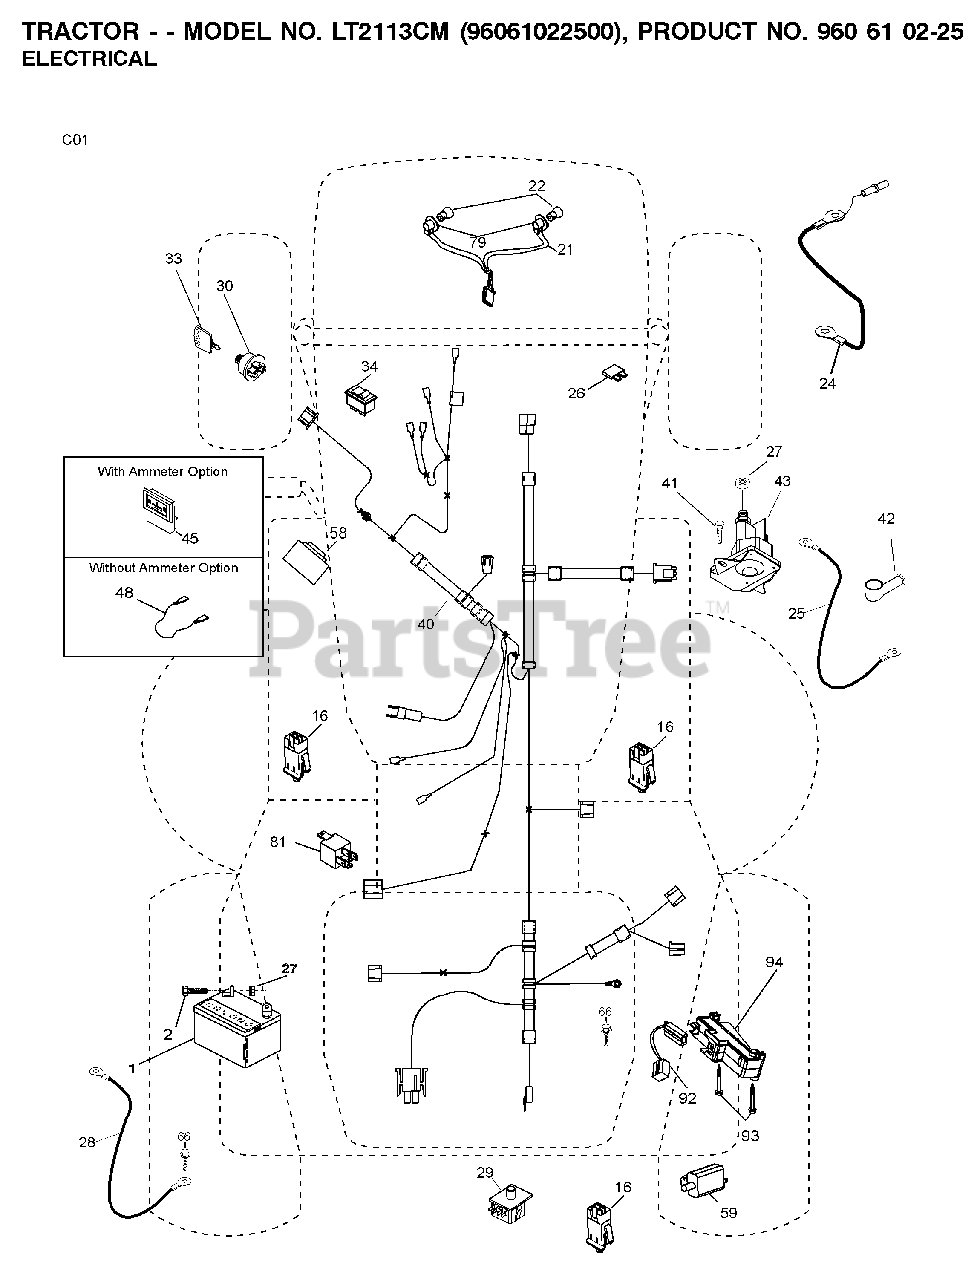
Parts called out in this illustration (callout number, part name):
1	REPL BY 532 12 38-99
16	SWITCH INTERLOOK PUSH-IN
21	HARNESS ASSY LIGHT
22	LIGHTBULB
24	BATTERY CABLE GT
25	CABLE BATTERY
26	FUSE 20AMP
27	NUT
28	CABLE GROUND
29	SWITCH.SEAT.DP W/RAMPS
30	SWITCH.IGN.DELTA.W.LGH.ROS
33	KEY.CHAIN.BLISTER.PACK.GEN.INT
34	SWITCH LT
42	TERMINAL COVER
43	SOLENOID.W/BRASS.PLUNG
58	BUZZER
79	BULB HOLDER ASM.
81	RELAY.ASSY.T
92	HARNESS.PIGTAIL.CONSLE
93	SCREW.PLASTITE
94	MODULE.REVERSE.ROS
